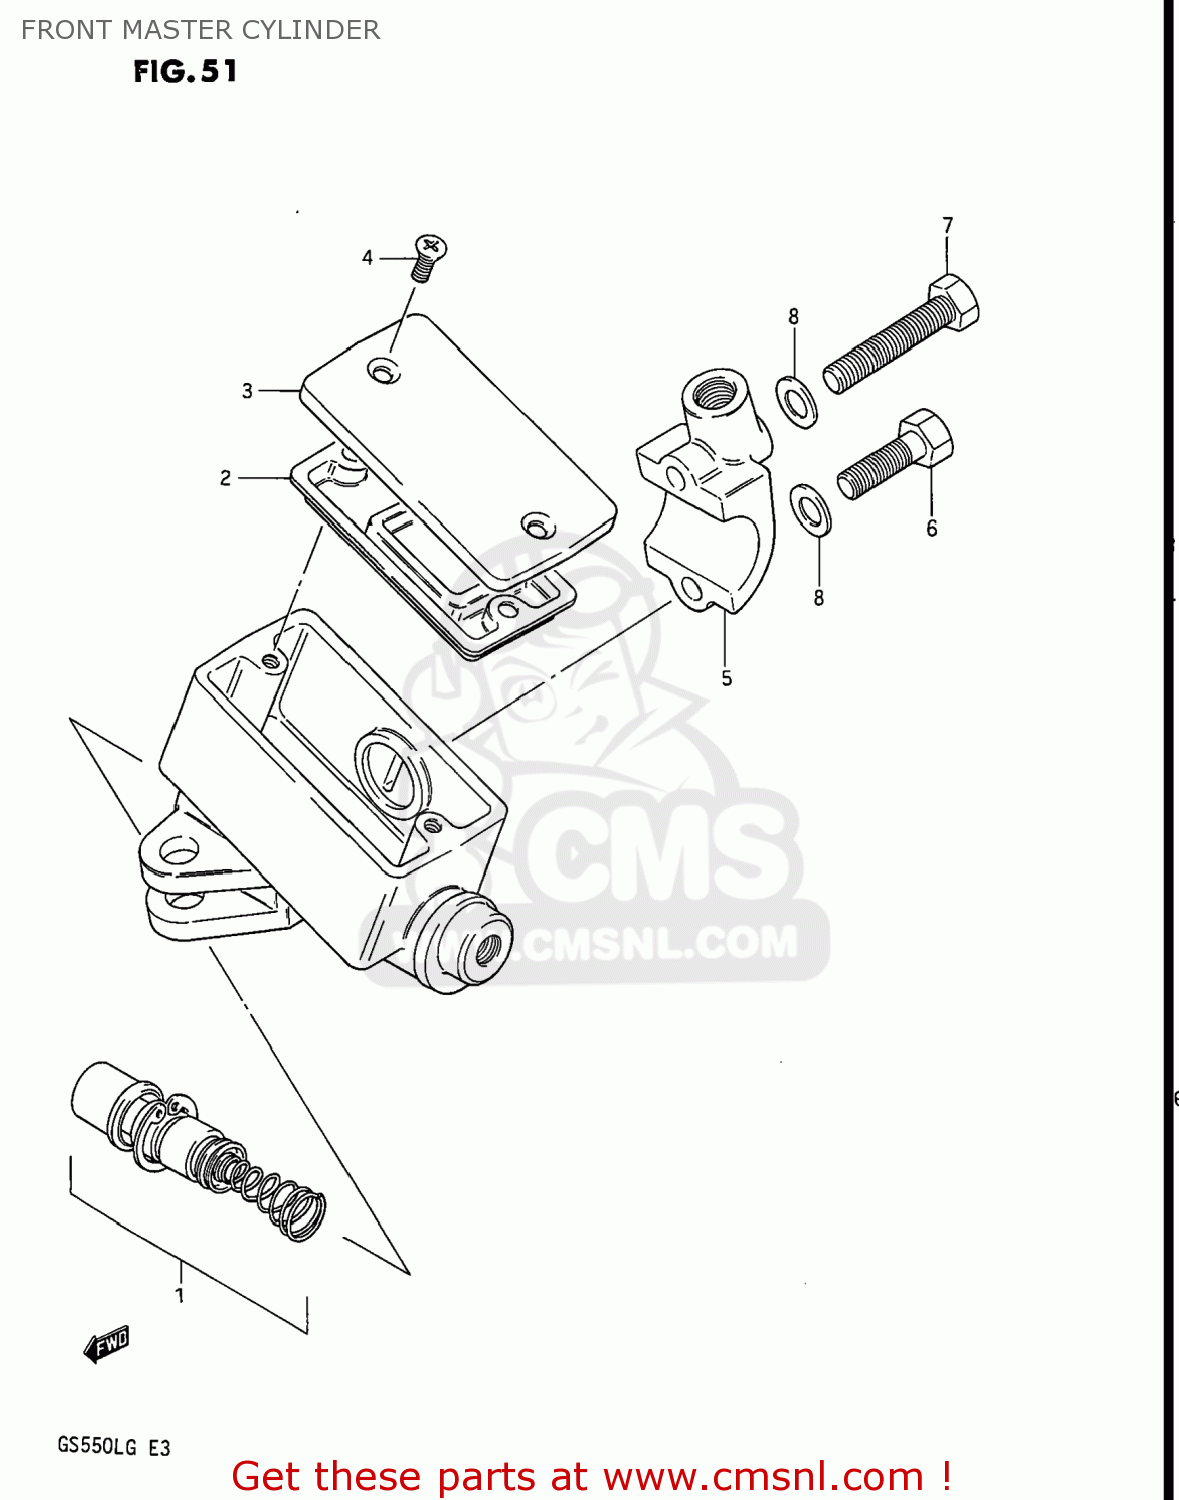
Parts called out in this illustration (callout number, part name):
1	CUP SET,MASTER CYLINDER
2	3
3	CAP
4	SCREW
5	HOLDER
6	BOLT
7	BOLT
8	WASHER
